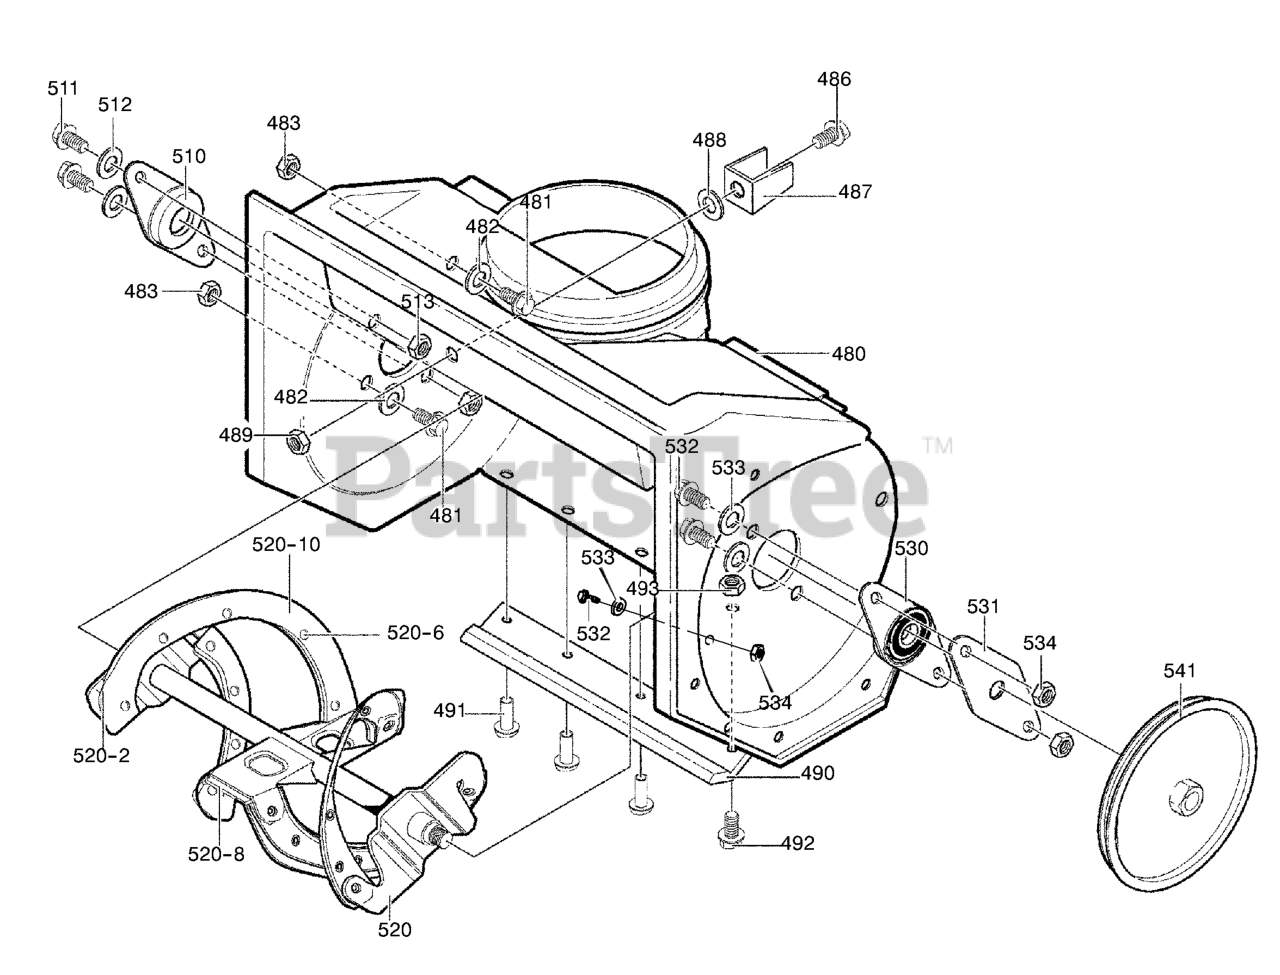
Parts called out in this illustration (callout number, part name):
480	HOUSING, ASSY
481	SCREW, 1/4-20X.75
482	WASHER, FLAT
483	NUT, 1/4-20
486	SCREW, 1/4-20X.63
487	BRACKET, STOP
488	WASHER, FLAT
489	NUT, 1/4-20 HEX NYLOCK
490	BLADE, SCRAPER
491	RIVET
492	SCREW, 1/4-20X.75
493	NUT, 1/4-20
510	BEARING, FLANGE
511	SCREW, 1/4-20X1.00
512	WASHER, FLAT
513	NUT, CNTRLK 1/4-20
520	AUGER, ASSY
520-2	BLADE, AUGER
520-6	RIVET
520-8	BLADE, CENTER
520-10	AUGER & BLADE SUPPORT
530	BEARING & PLATE ASSY
531	PLATE, RETAINER
532	SCREW, 1/4-20X.63
533	WASHER, FLAT
534	NUT, 1/4-20
